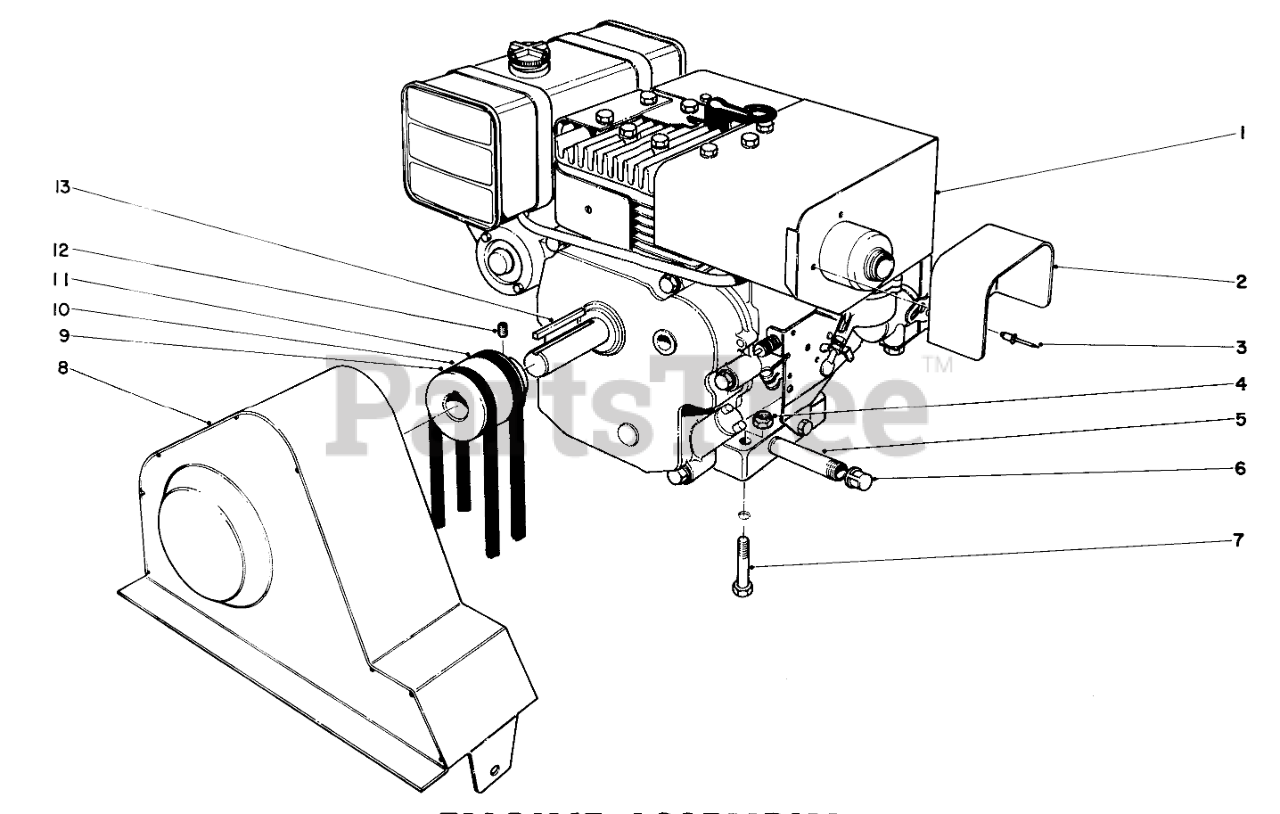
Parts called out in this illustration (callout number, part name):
1	Engine (Recoil)
2	Shield, Muffler
3	.187 X 1/4 POP RIVET
4	NUT-LOCK, NI
5	NIPPLE-PIPE
6	CAP-PIPE
7	SCREW-HH
8	Belt Cover
9	V-Belt
10	Pulley, Engine
11	V-Belt, Drive
12	SCREW-SET, HSH
